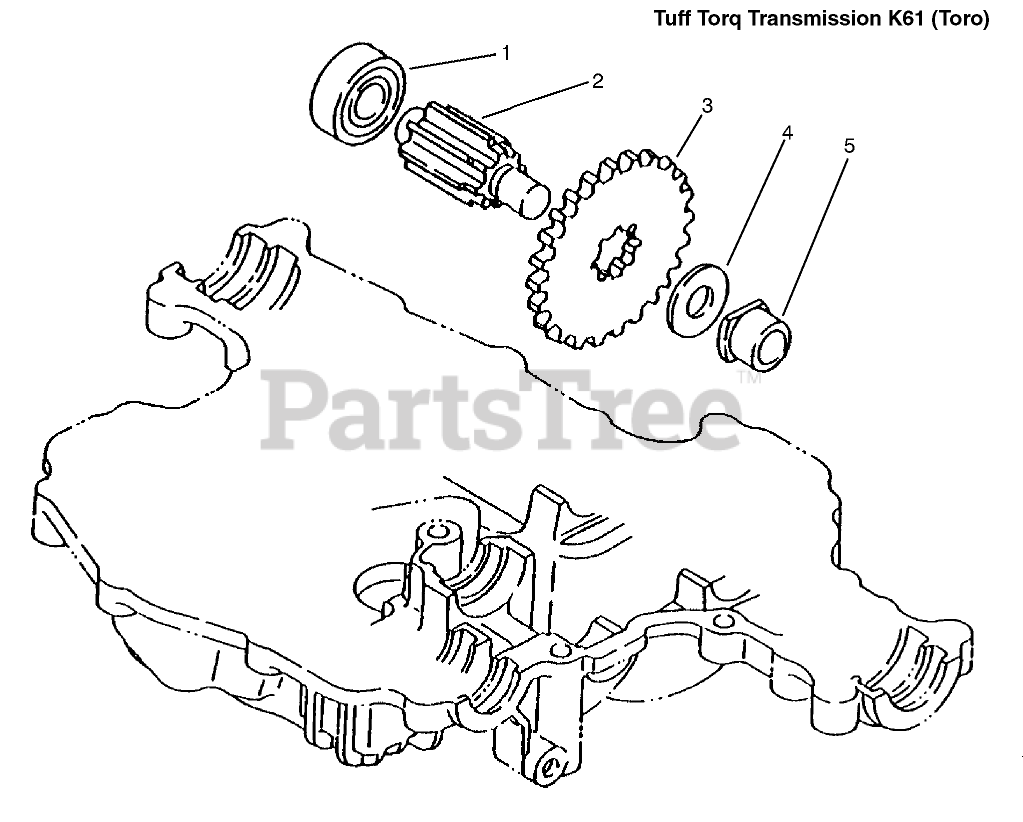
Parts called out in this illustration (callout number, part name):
1	BEARING
2	SHAFT - FINAL PINION
3	GEAR-FINAL SHAFT
4	WASHER
5	BUSHING
